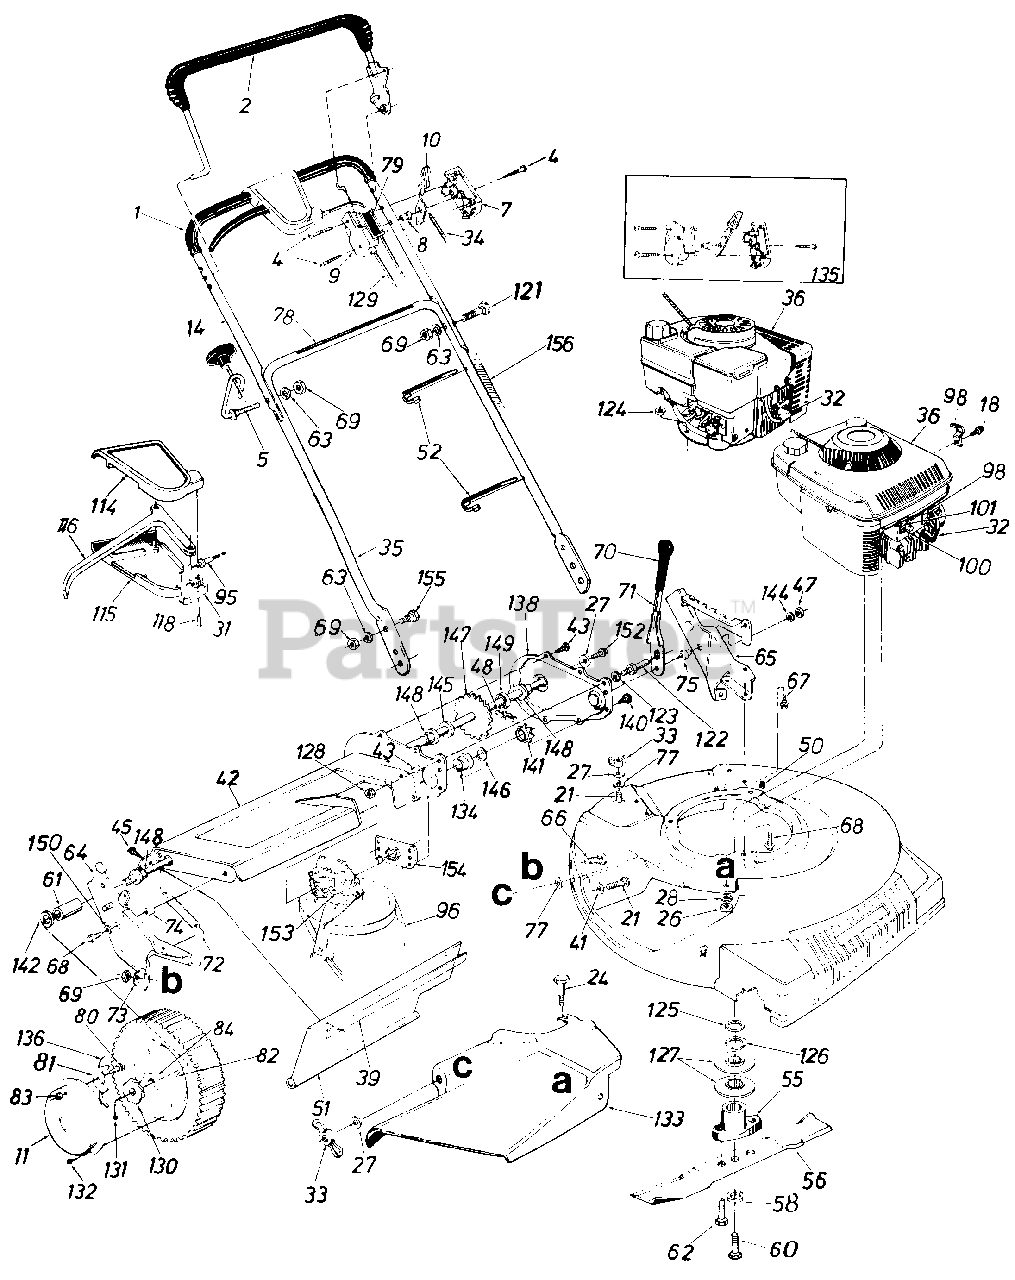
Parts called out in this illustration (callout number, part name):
2	Control Handle Ass'y. L.H.
4	Truss Mach. Scr. #12 x 1.50" Lg.
5	Rope Guide Bolt
7	Control Panel Half
8	Control Disc Pin
9	Clutch Panel Half
10	Throttle Control Lever
11	Hub Cap
14	Upper Handle Chrome
18	Hex B-Tap Scr. #10 x .38"
21	Carriage Bolt 1/4-20 x .62"
24	Shoulder Bolt .312 Dia. x .18 Lg. Special
26	Hex Nut 1/4-20 Thd.
27	Bell-Wash. 1/4" I.D.
28	L-Wash. 1/4" I.D.
31	S.P. Control Cover
32	Spark Plug Insulator
33	Wing Nut
34	Throttle Control Wire 58"
35	Lower Handle Chrome
36	Engine
39	Retaining Strip
41	Fl-Wash. .344" I.D. x .62"
42	Chain Axle Ass'y.
43	Hex B-Tap Scr. 1/4" X .38"
45	Hex AB-Tap Scr. 1/4 X .62"
47	Hex Patch L-Nut 3/8-24 Thd.
48	#48 Chain .500" Pitch x .30 Links
51	Rear Flap 3.75" x 17.30" Lg.
52	Cable Tie
55	Blade Adapter
56	21" Blade
58	Bell-Wash. .460" I.D. x 1.38"
60	Hex Bolt 7/16-20 x 1.5"
61	Spacer.513" I.D.
62	Hex L-Wash. Scr. 3/8-16 x .75"
64	R.H. Handle Wheel Brkt. Ass'y.
65	L.H. Handle Wheel Brkt. Ass'y.
66	Carriage Bolt 5/16-18 x .62"
67	Hex Wash. Hd. B-Tap Scr. 5/16-18
68	Hex Wash. Hd. TT-Tap Scr. 3/8-16
69	Hex Nut 5/16-18 Thd.
71	Height Adj. Lever
72	Extension Spring 3.80" Lg.
73	Bell-Wash. 5/16" I.D.
74	Spacer .385" I.D.
75	Shld. Spacer.5" Dia.
77	Bolt Retainer 1/4 x .50" O.D.
78	Instruction Label 0287040002
79	Control Label
80	Shld. Scr. .342" Dia. x .268
81	Pawl
82	Wheel Ass'y. Comp. Rear
83	Hex Ins. L-Nut 1/4-20 Thd.
84	Flange Ball Bearing 1/2" I.D.
95	S.P. Cable x 50" Lg.
96	"V"-Belt
98	Casing Clamp
100	Hex B-Tap Scr. #10 x .62"
101	Casing Clamp
115	Self-Propelled Control Cover
116	Control Lever
118	Fl-"C"-Sunk Hd. Tap Scr. #10 x .75" Lg.
121	Curved Carr. Bolt 5/16-18 x 1.75" Lg.
122	Shld. Pin 1.43" Lg.
123	L-Wash. 3/8" I.D.
124	Hex Nut 3/8 x 16 Thd.
125	Serrated Wash. 1.0" I.D.
126	Wave Wash. 1.005" I.D.
127	Serrated Pulley Half
128	Hex Nut 3/8-24 Thd.
129	Control Cable 46"
130	Ratchet Wheel 1.62" O.D.
131	Cotter Pin 1/8" Dia. x 1"
132	Pan Hd. Tap Scr. #12 x .50"
133	Side Chute Deflector Ass'y.
134	Flange Bearing
135	Kit Control Housing Comp.
136	Spring Nylon
138	Chain Cover
140	Hex Wash. S.Tap Scr. 1/4-20 x.50" Lg.
141	Sprocket Shaft Ass'y.
142	Fl-Wash. .510" I.D. x 1.0" 0287040002
144	Fl-Wash. .385" I.D. x .87"
145	Fl-Wash. .51" I.D. x 1.0"
146	Fl-Wash. 3/8" I.D.
147	Rear Shaft Ass'y. 21.94" Lg.
148	Hex Flange Brg. .506" I.D.
149	Fl-Wash. .531" I.D. x .930"
150	Fl-Wash. 3/8" I.D.
152	Hex Bolt 1/4-20 x .62" Lg. (Grade 5)
153	Transmission Comp.
154	Hex Bearing Cup
155	Truss Mach. Scr. 5/16-18 x .75" Lg.
156	Plastic Tubing
